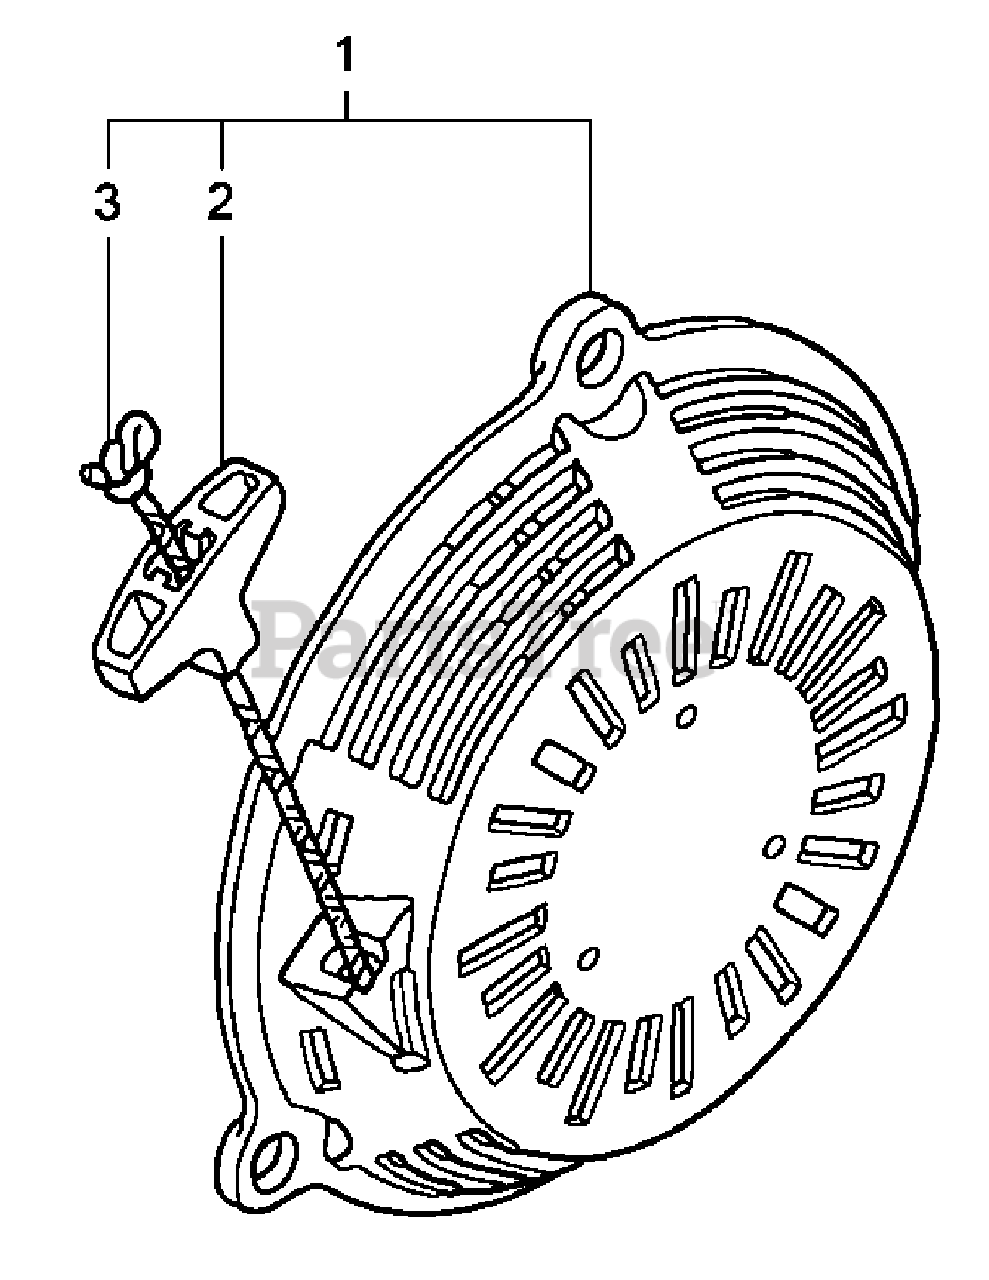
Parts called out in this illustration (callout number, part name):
1	Starter Assembly, Recoil
2	Grip, Starter
3	Rope, Recoil Starter
